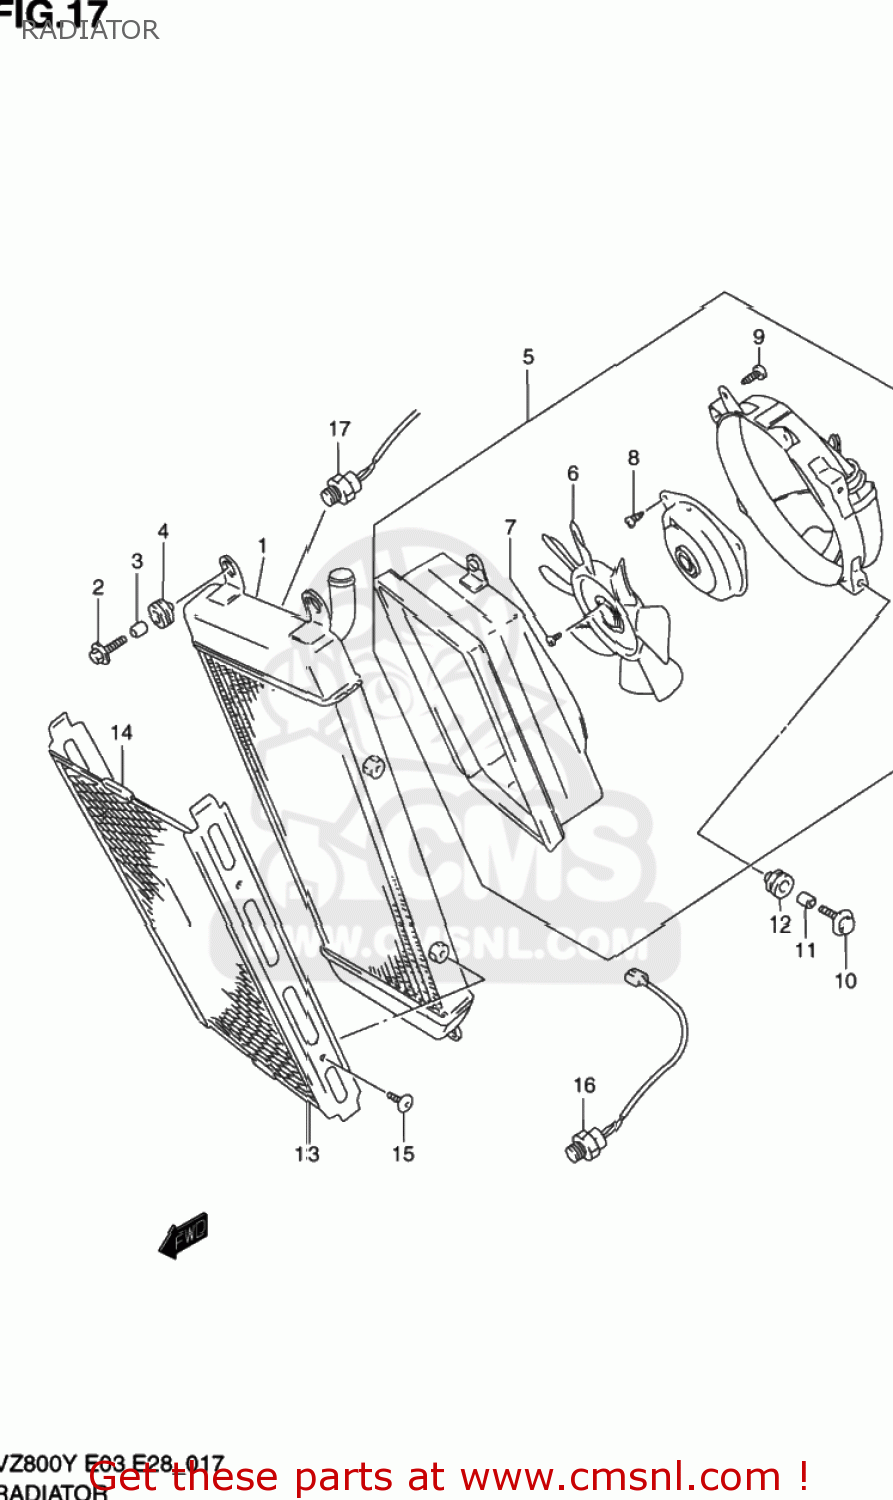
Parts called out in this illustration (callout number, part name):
1	RADIATOR ASSY,WATER
2	BOLT(6X20)
3	SPACER(6.5X10X10)
4	CUSHION
5	FAN ASSY,RADIATOR
6	FAN
7	SCREW 4X6
8	SCREW
9	SCREW 5X12
10	BOLT(6X20)
11	SPACER(6.5X10X10)
12	CUSHION
13	COVER,RADIATOR
14	PROTECTOR,CTR
15	SCREW(6X10)
16	SWITCH,RADIATOR FAN
17	SWITCH ASSY,WATER TEMP
